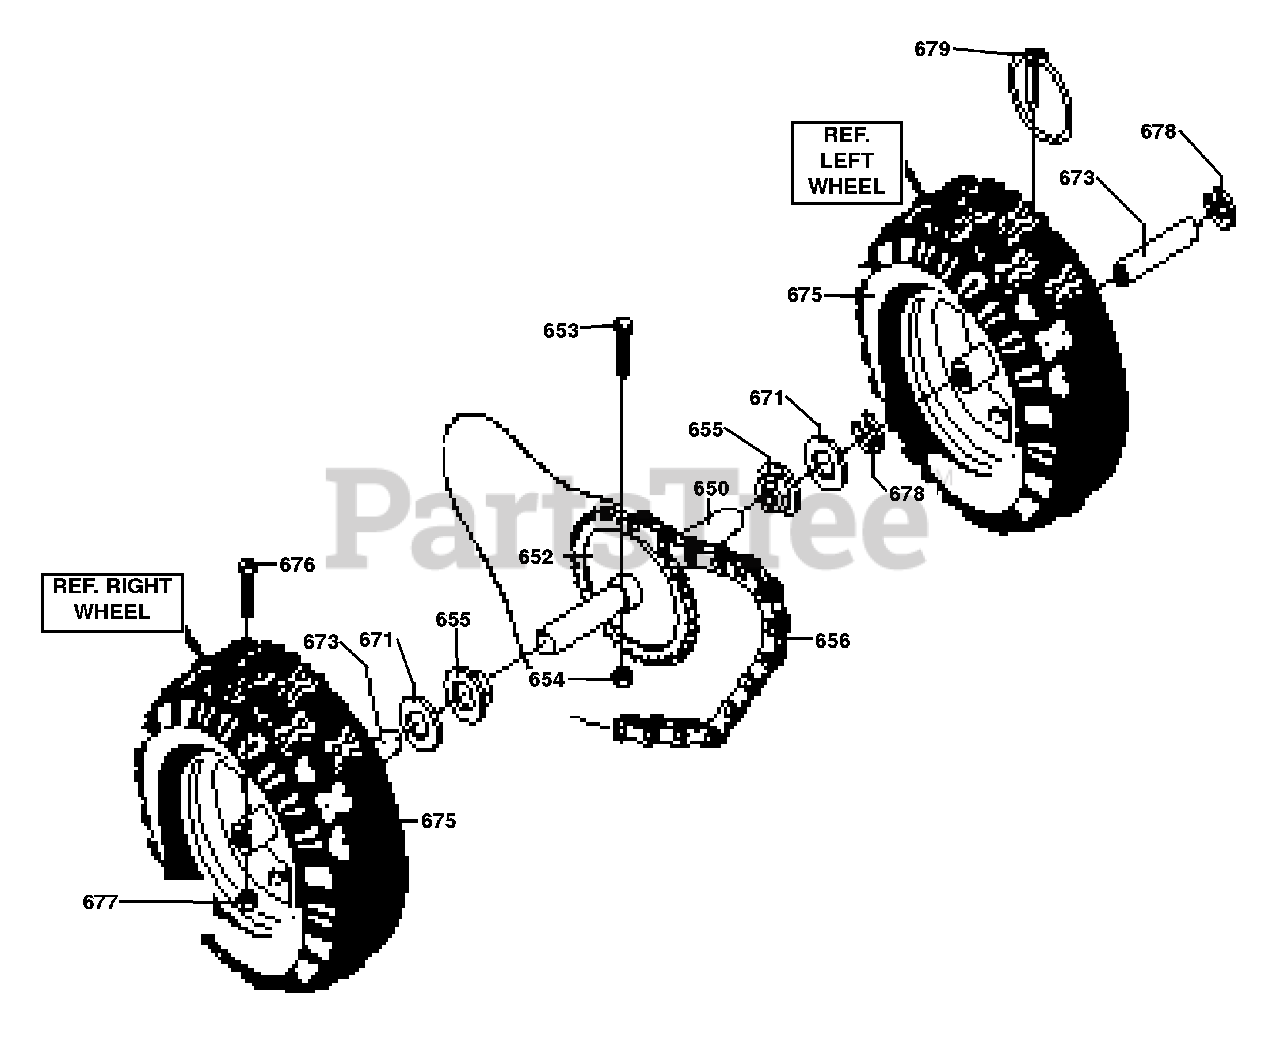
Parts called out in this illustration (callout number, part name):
650	SHAFT, AXLE
652	SPRKT & HUB
653	SCREW, 1/4-20 X 2.25
654	NUT, 1/4-20
656	CHAIN, ROLLER
671	FLATWASHER
673	BUSHING, WHEEL
675	TIRE & RIM
676	SCREW, 1/4-20 X 1.75 HH
677	NUT, 1/4-20 REGHXCTRLK
679	PIN, KLIK .25 X 1.38 DIA
